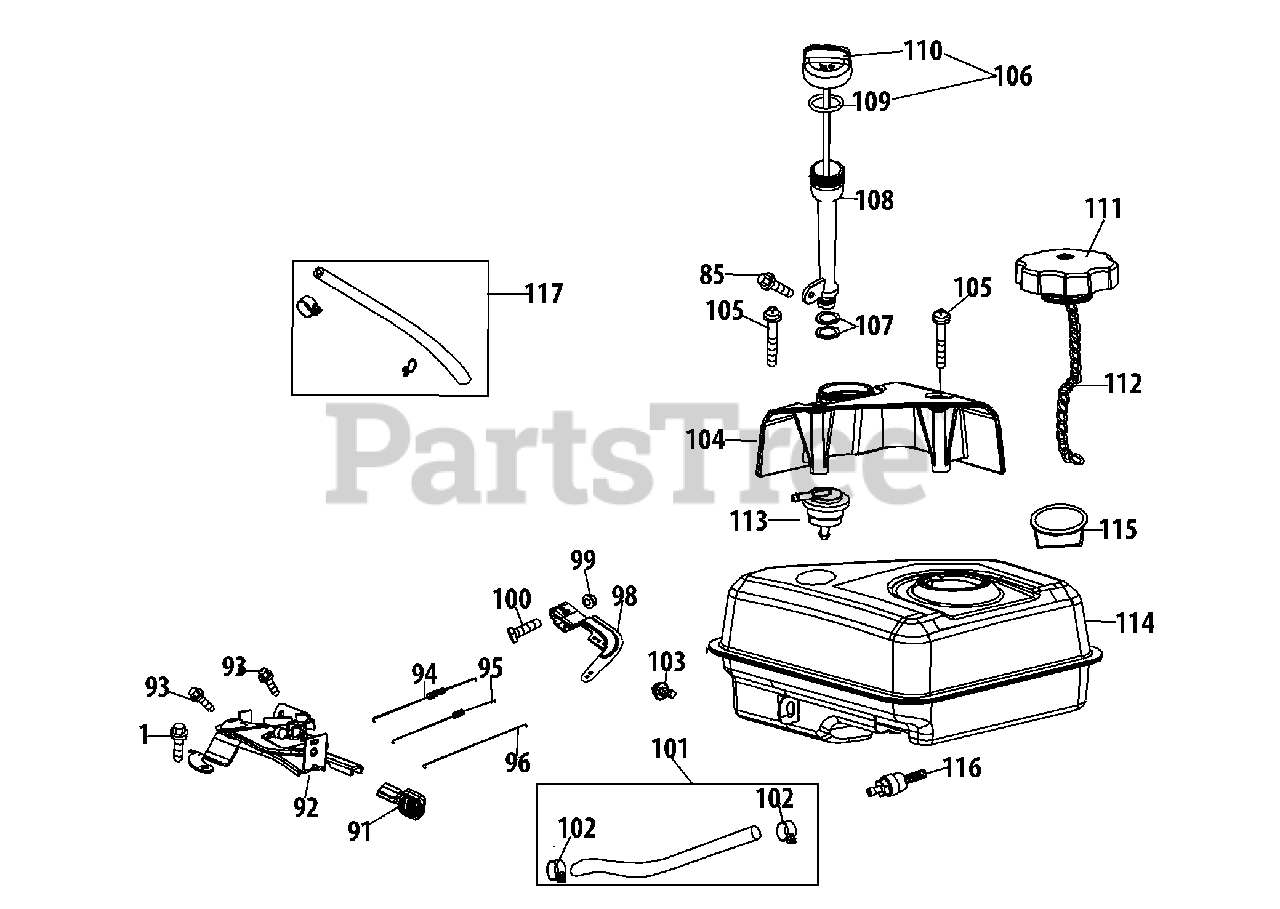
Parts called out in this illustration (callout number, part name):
1	Bolt M6×16
91	Throttle Control Knob
92	Primer Bracket
93	Bolt M6×12
94	Governor Spring
95	Throttle Linkage Spring
96	Throttle Linkage
98	Governor Arm
99	Nut M6
100	Governor Arm Bolt
101	Fuel Line Kit
102	Fuel Hose Clamp
103	Bolt M6×12
104	Dipstick Decoration Cover
106	Oil Fill Tube Assembly
107	Fill Tube O-Ring
108	Dipstick Tube
109	Dipstick O-Ring
110	Dipstick Assy
111	Cap Comp,Fuel Feller
112	Fuel Cap Tether
113	Roll Over Valve
114	Fuel Tank
115	Fuel Level Indicator
116	Fuel Tank Nipple
117	Evap Hose Assembly
